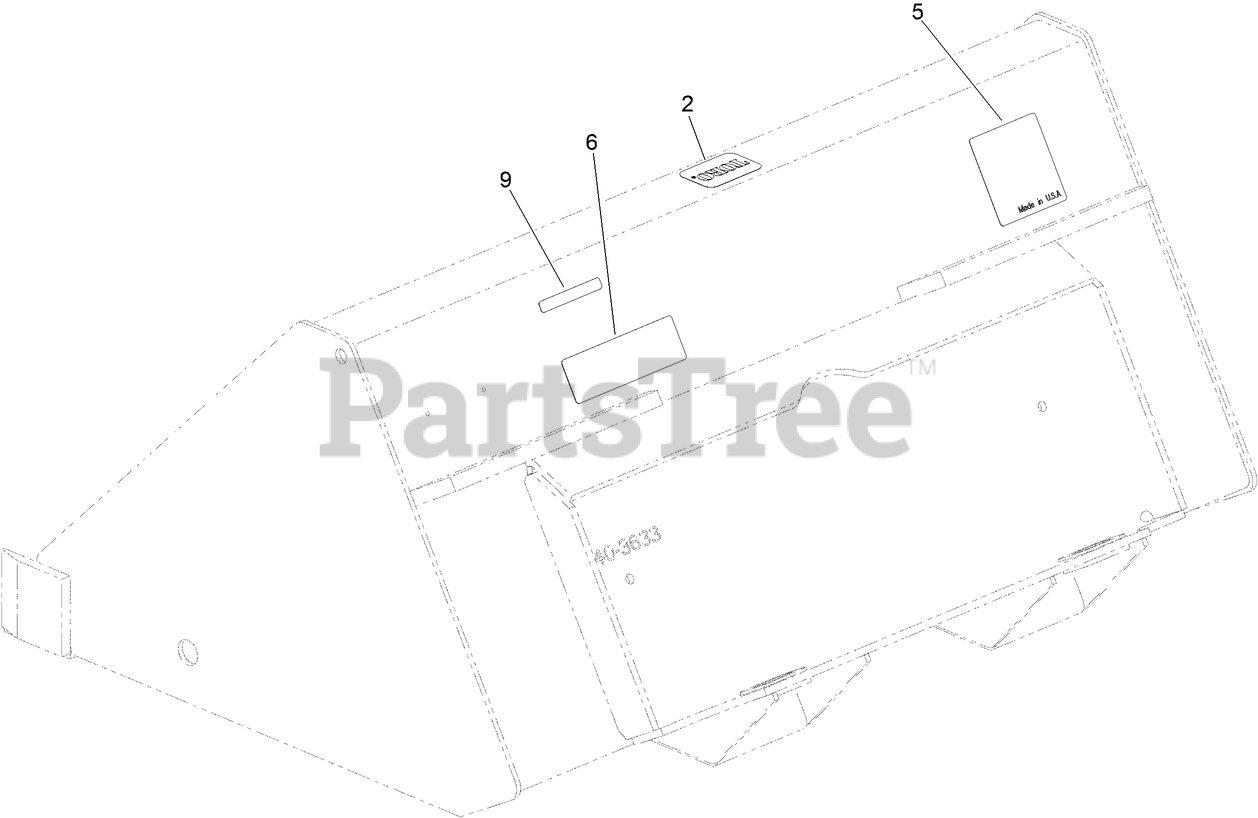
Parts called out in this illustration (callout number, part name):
2	DECAL
5	DECAL
6	DECAL - CAPACITY
9	DECAL-WARNING
